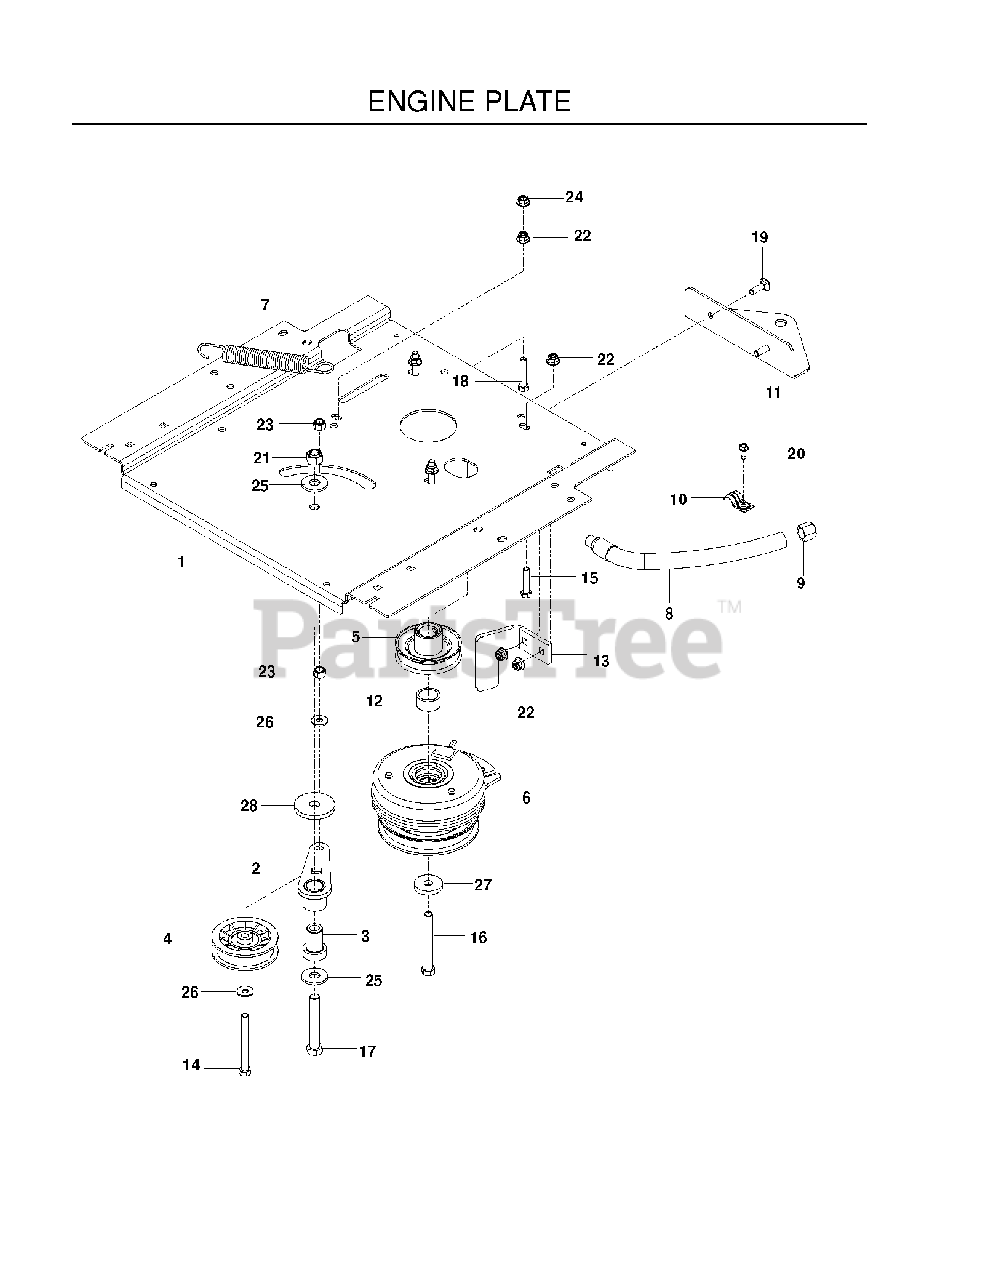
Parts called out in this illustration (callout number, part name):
1	PLATE, ENGINE BLK
2	IDLER ARM WELDMENT
3	IDLER SPINDLE
4	PULLEY, IDLER
5	PULLEY, ENGINE
6	CLUTCH, 105 FT-LBS
7	SPRING, DECK DRIVE
8	OIL DRAIN HOSE
9	DRAIN CAP
11	HITCH, BLACK
12	T & B SPACER
13	STOP, CLUTCH, BLACK
14	HCS 3/8-16X3 1/2 GR5
15	CAPSCREW 5/16 X 1/1/2 HEX HEAD
16	HCS 7/16-20X3-1/2 GR 5 ZN
17	HCS 1/2C X 3 1/4
18	HCS 5/16C X 1 3/4
19	RHSNB 5/16C X 1
20	SCREW 1/4 X 5/8
21	NUT 1/2-13 HEX NYLOC ZD
22	5/16-18 NYLOC FLANGE NUT
23	NUT 3/8-16 NYLOC
24	NUT 5/16C WHIZ
25	WASH USS FLAT 1/2
26	WASHER 5/16 FLAT
27	CLUTCH, WASHER
28	HEAVY WASHER
